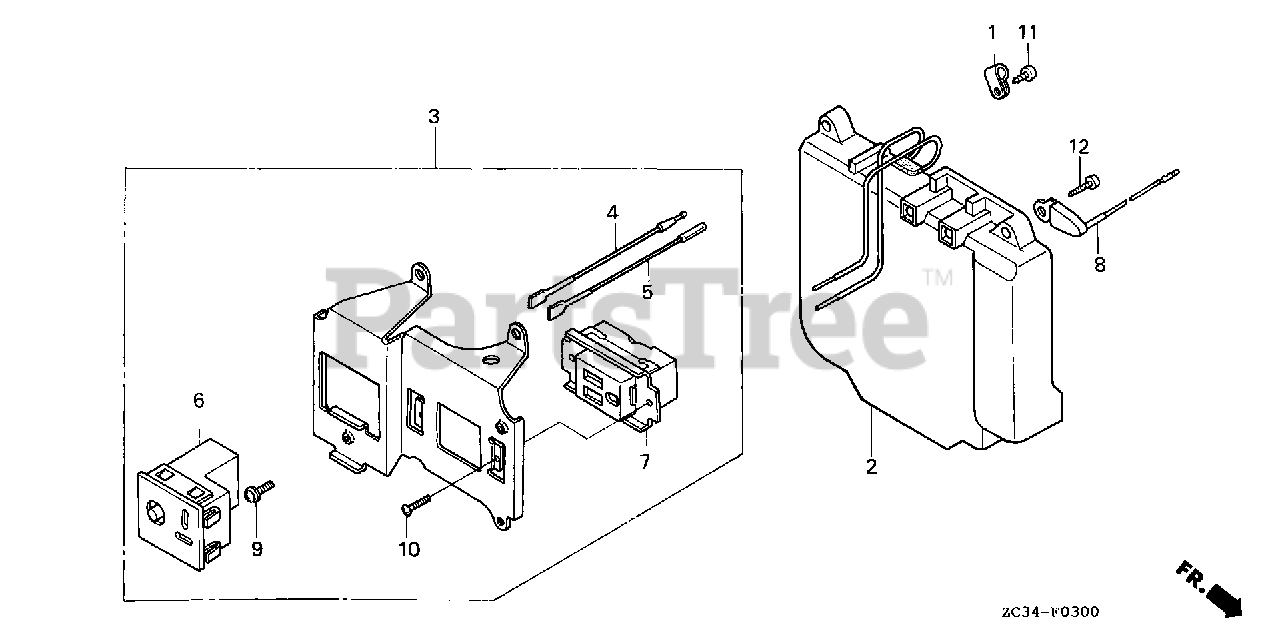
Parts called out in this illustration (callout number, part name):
1	CLAMP A, CABLE
2	INVERTER UNIT (A)
3	PANEL ASSY., RECEPTACLE
6	RECEPTACLE, D.C. (6.3A)
7	RECEPTACLE (15A/125V)
8	SWITCH ASSY., INCLINATION
9	SCREW, PAN (5X12)
10	SCREW, PAN (3X8)
11	SCREW, TAPPING (5X12)
12	SCREW, TAPPING (5X25)
